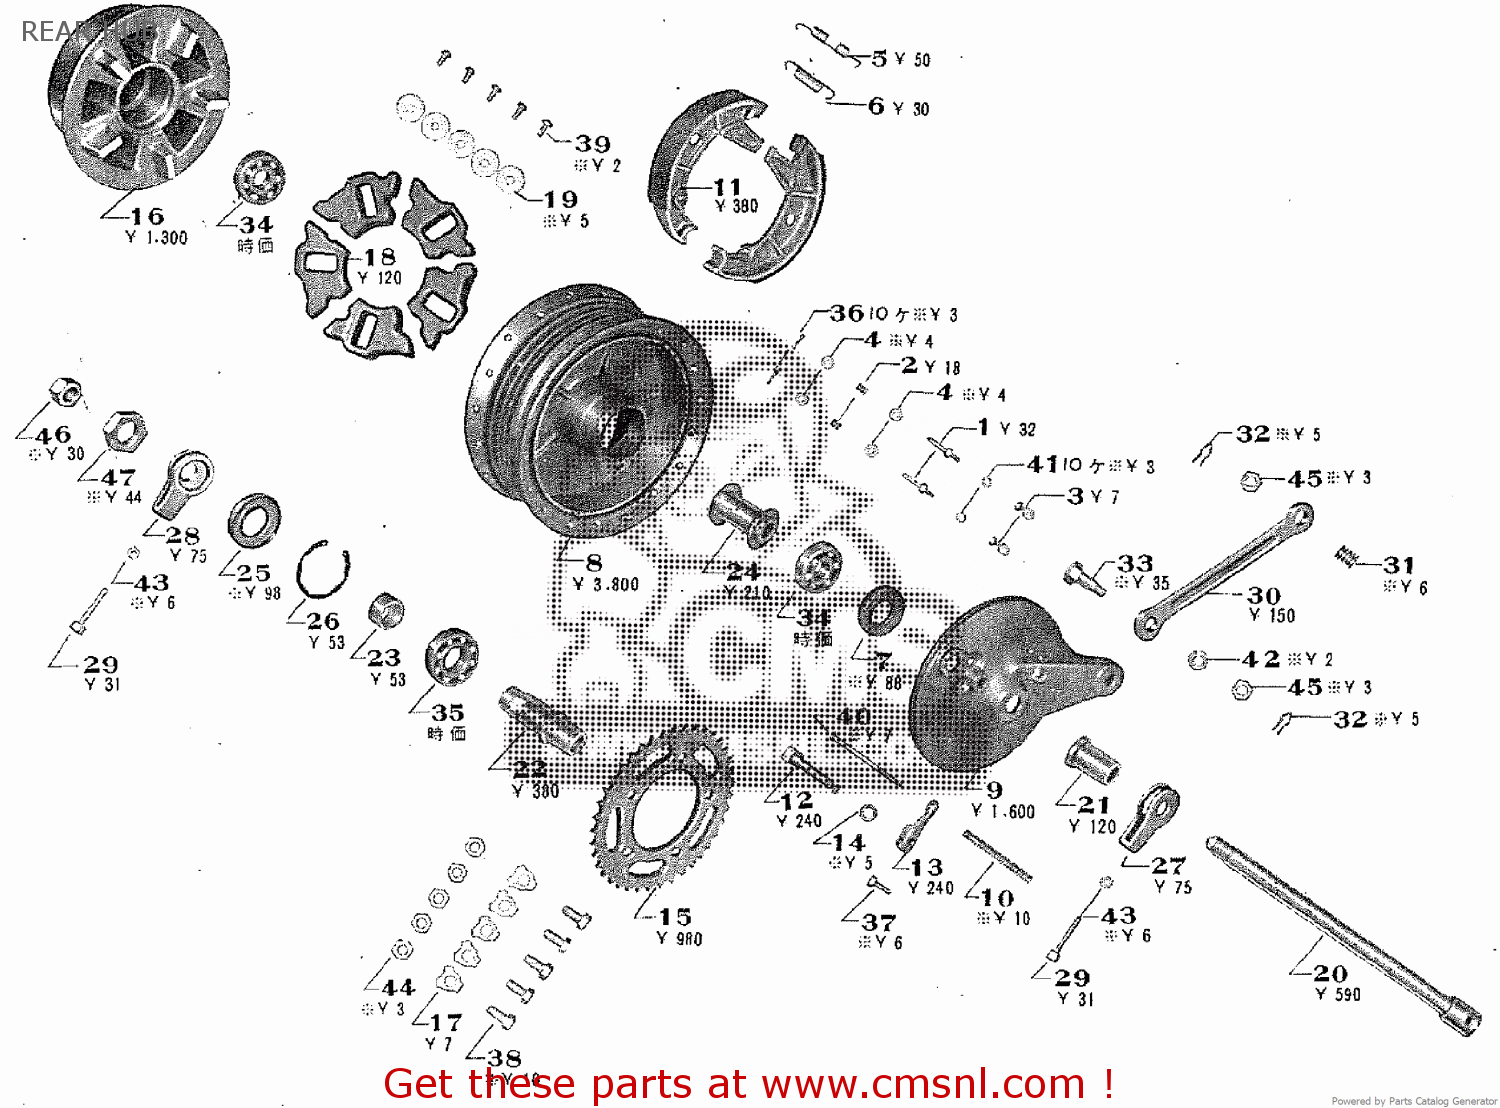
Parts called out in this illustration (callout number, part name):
1	SHOE SUPPORTER SET BOLT
2	SHOE SUPPORTER SPRING
3	SHOE SLIDE PLATE
4	SHOE SUPPORTER SET WASHER
5	SHOE RETURN UPPER SPRING
6	SHOE RETURN SPRING
7	HUB DRUM OIL SEAL
8	REAR HUB ASSY.
9	REAR PANEL COMP.
10	SHOE ADJUSTER SPRING
11	REAR BRAKE SHOE COMP.
12	REAR ADJUSTER CAM
13	REAR ADJUSTER ARM
14	ADJUSTER CAM WASHER
15	DRIVEN SPROCKET
16	SPROCKET SUPPORTER
17	SPROCKET SET WASHER
18	SHOCK ABSORBER
19	WASHER
20	REAR HUB SHAFT COMP.
21	REAR HUB SHAFT COLLAR
22	SPROCKET SUPPORTER SHAFT
23	SPROCKET SUPPORTER COLLAR
24	REAR BEARING DISTANCE COLLAR
25	HUB DRUM OIL SEAL
26	BEARING CIRCLIP
27	RIGHT CHAIN ADJUSTER COMP.
28	LEFT CHAIN ADJUSTER COMP.
29	CHAIN ADJUSTER BOLT
30	REAR TORQUE LINK COMP.
31	SPRING
32	REAR TORQUE LINK SET CLIP
33	BOLT
34	BEARING
35	BALL BEARING
36	2.0X12 COTTER PIN
37	6X18 HEXAGON BOLT
38	10X20 LIGHT HEXAGON BOLT
39	6X12 CROSS SCREW
40	6X75 CROSS SCREW
41	5MM SPRING WASHER
42	10MM SPRING WASHER
43	6MM HEXAGON NUT
44	10MM HEXAGON NUT
45	10MM HEXAGON NUT
46	16MM LIGHT HEXAGON NUT
47	24MM LIGHT HEXAGON NUT
